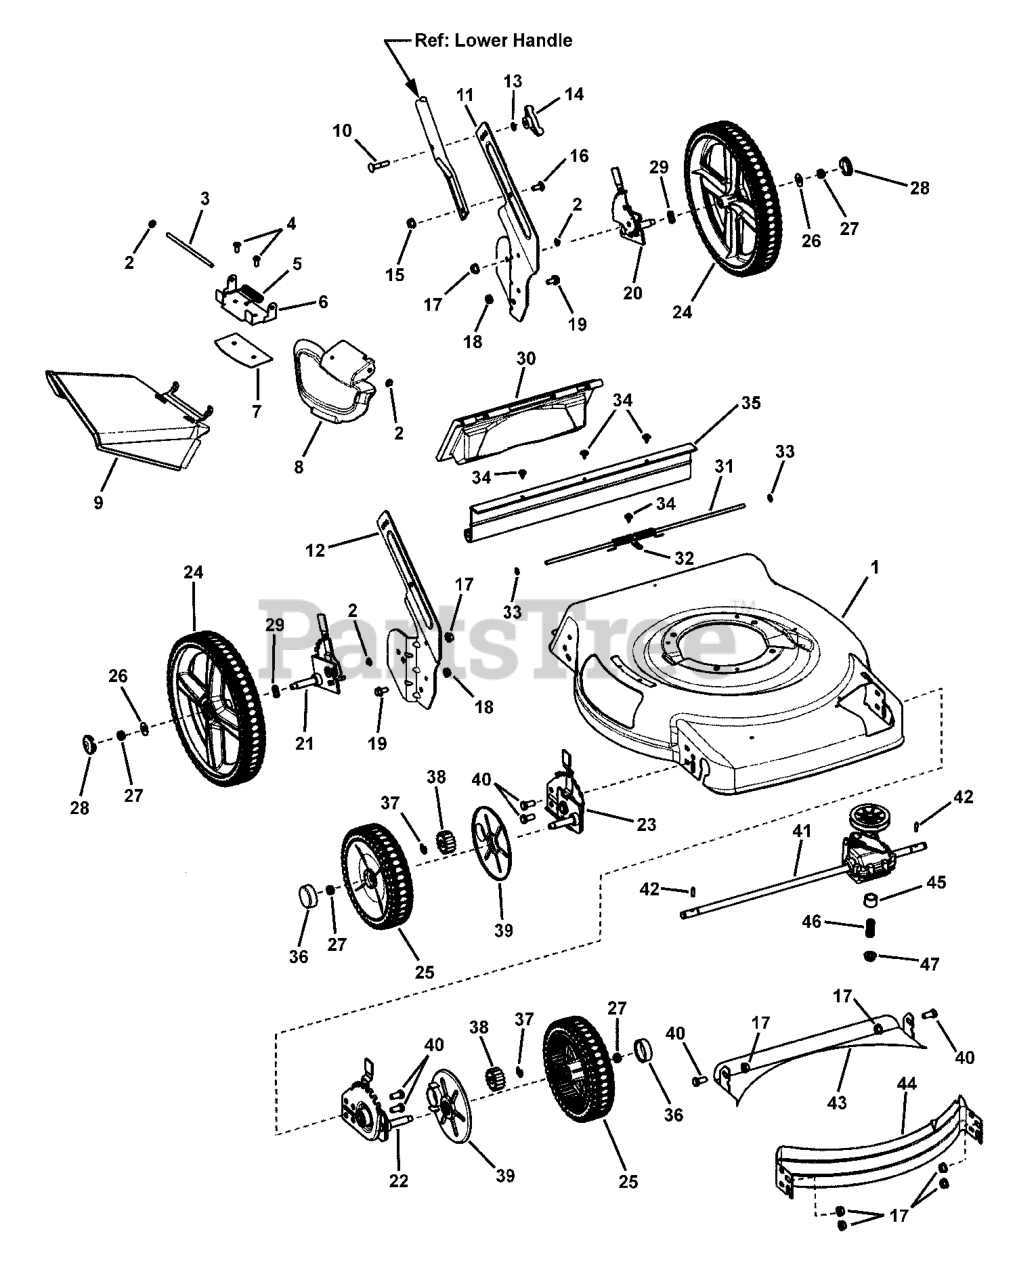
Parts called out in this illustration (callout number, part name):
1	DECK, 22" Walk, 3-N-1
2	PUSHNUT, 1/4"
3	ROD, Chute Pivot - 1/4" Dia. x 5.55"
4	SCREW, 1/4-20 x 11/16" Pan Head Self-Tap - Torx
5	SPRING, Chute - Torsion
6	BRACKET, Chute
7	PLATE, Mulch, 22" RB Scott's
8	COVER, Mulch, Plastic, Black
9	SIDE CHUTE, Plastic, Black
10	BOLT, 5/16-18 x 1-1/2" Square Neck Carriage
11	BRACKET, Lower Handle, LH, 22" WBM, Hi-Wheel
12	BRACKET, Lower Handle, RH, 22" WBM, Hi-Wheel
13	WASHER, 5/16" Internal Tooth Lock
14	KNOB, 5/16-18 Wing - Black
15	NUT, 5/16-18 Large Flange Center Lock
16	BOLT 5/16-18 x 3/4" Round Head Short Square Neck
17	NUT, 3/8-16 Hex Flange Lock, GR 5
18	NUT, 5/16-18 Flange Lock
19	BOLT, 5/16-18 x 5/8" Hex Flange Lock
20	ASSY, Height-of-Cut, Left Rear, 7 Position
21	ASSY, Height-of-Cut, Right Rear, 7 Position
22	ASSY, Height-of-Cut, Left Front, 22" WBM, Self-Prop, 7 Position
23	ASSY, Height-of-Cut, Right Front, 22" WBM, Self-Prop, 7 Position
24	ASSY, Wheel, 12" x 2" Idle, NB, Murray Tread, Gray
25	ASSY, Wheel, 8" x 2" Drive, NB, Murray Tread, Gray
26	WASHER, 1" O.D. x .387 I.D. Flat
27	NUT, 3/8-16 Hex Center Lock, YZ
28	HUBCAP, 12" Wheel, Gray
29	WASHER, .531 x .781 3-Wave
30	DOOR, Rear Discharge, 22" Walk Mower
31	ROD, Pivot, Rear Door - 1/4" Dia. X 17-1/2"
32	SPRING, Torsion, Rear Door, 22" Walk Mower
33	CAP, Retainer
34	SCREW, #10-24 x 1/2" Hex Washer Self-Tap - Sems
35	GUARD, Rear 22" Hi-Wheel
36	HUBCAP, Round, Black
37	RING, External Retaining
38	GEAR, Pinion, 22" WBM, FWD
39	SHIELD, Dust, 22" WBM, FWD
40	SCREW, 3/8-16 x 3/4" Hex Head Cap, GR 5
41	TRANSMISSION, 22" WBM Single Speed, Front Wheel Drive
42	DRIVE PIN, 22" WBM, Front Wheel Drive
43	BAFFLE, Rear, 22" Deck
44	BAFFLE, Front, 22" WBM
45	SPACER, Engine
46	SPRING, Compression
47	NUT, 5/16-18 Hex Flange Lock
